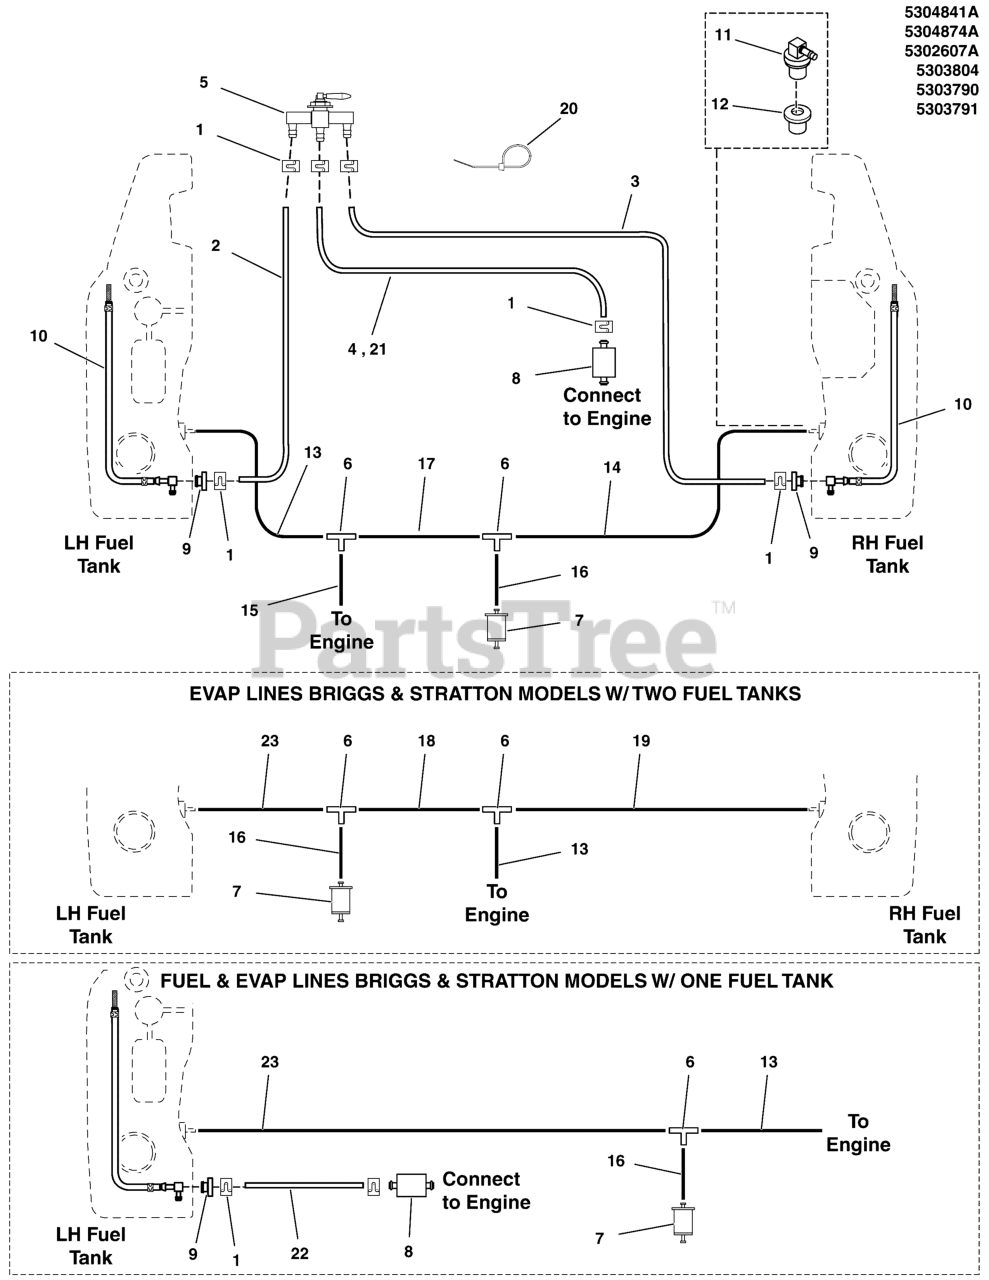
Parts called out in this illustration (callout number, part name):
1	CLAMP, Hose
2	HOSE, FUEL, 1/4 IN, LW PRMTN, 24" LONG
3	HOSE, FUEL, 1/4 IN, LW PRMTN, 26" LONG
4	HOSE, FUEL, 1/4 IN, LW PRMTN, 16" LONG
5	SEE FUEL TANK AND MOUNT GROUP
6	FITTING, 3/16" TEE, BARB TYPE, HDPE
7	FILTER, FUEL
8	FUEL FILTER (SV)
9	BUSHING-FUEL TANK RED RUBBER
10	PICKUP TUBE ASSEMBLY, FUEL LINE (SV)
11	REMOTE VENT ASSEMBLY
12	GROMMET (SV)
13	HOSE, VAPOR, 5MM ID, 12.00 LG
14	HOSE, VAPOR, 5MM ID, 21.00 LG
15	HOSE, VAPOR, 5MM ID, 16.50 LG
16	HOSE, VAPOR, 5MM ID, 2.00 LG
17	HOSE, VAPOR, 5MM ID, 17.50 LG
18	HOSE, VAPOR, 5MM ID, 5.00 LG
19	HOSE, VAPOR, 5MM ID, 22.00 LG
20	TIE, SELF-LOCKING, 6"
21	1/4" Fuel Line, 5" Long
22	HOSE, FUEL, 1/4 IN, LW PRMTN, 24" LONG
23	HOSE, VAPOR, 5MM ID, 26.00 LG
